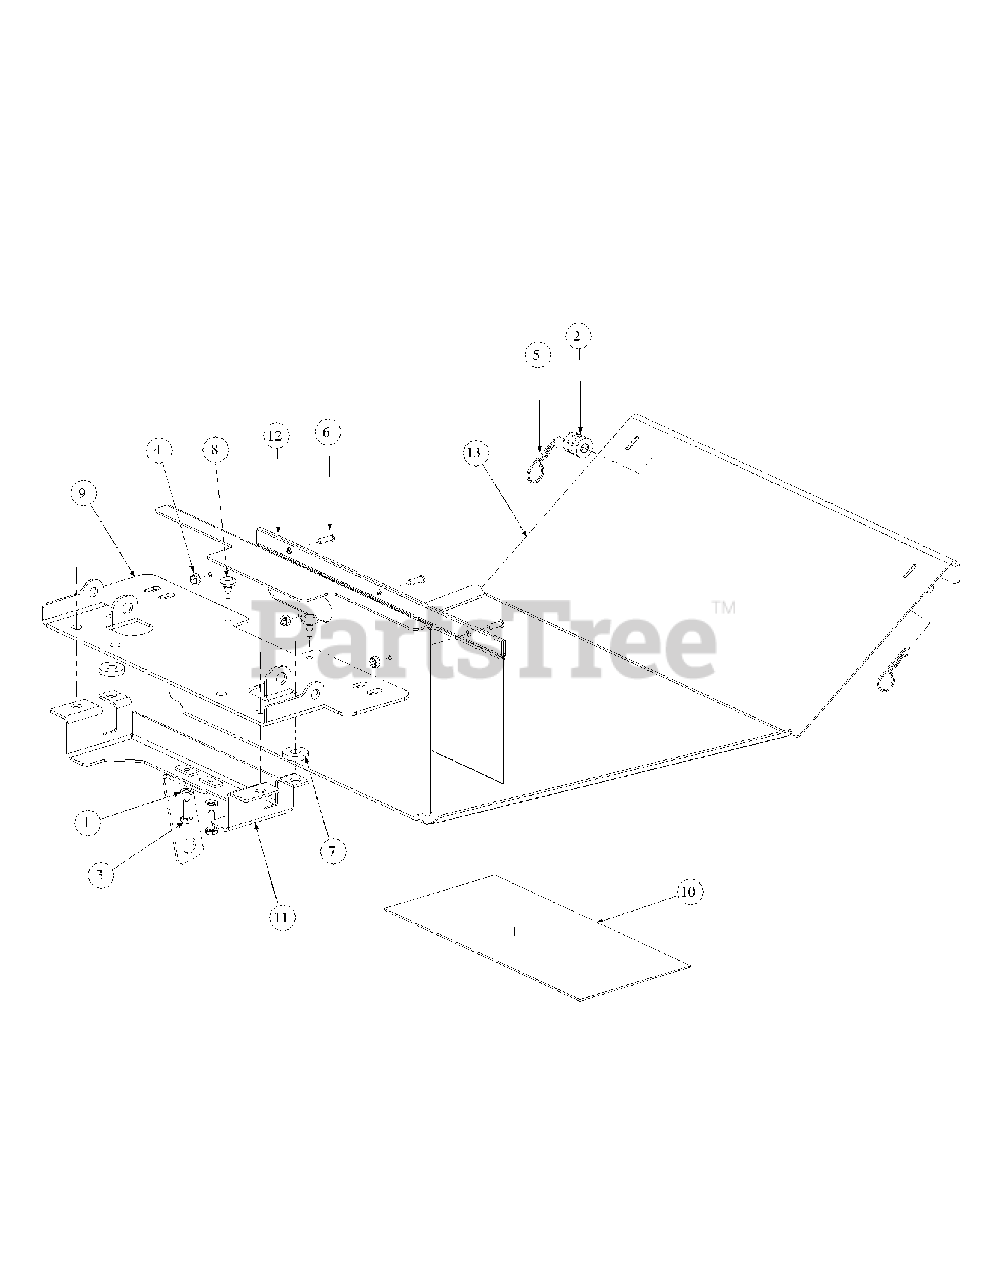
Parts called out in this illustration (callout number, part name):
1	Lock Washer, 1/4
2	Washer
3	Hex Cap Screw, 1/4-20, .75
4	Lock Nut, Nylon Insert, 10-32
5	Hair Pin, 3/8-1/2
6	Screw, Phillips Head, Machine, 10-32 x 5/8
7	Washer
8	Rubber Bumper, .62 OD x .22 Thick
10	Label, Belt Routing and Lubrication
11	Support, Seat Bracket
12	Bag, Debris Storage
13	Floor Panel Assembly
